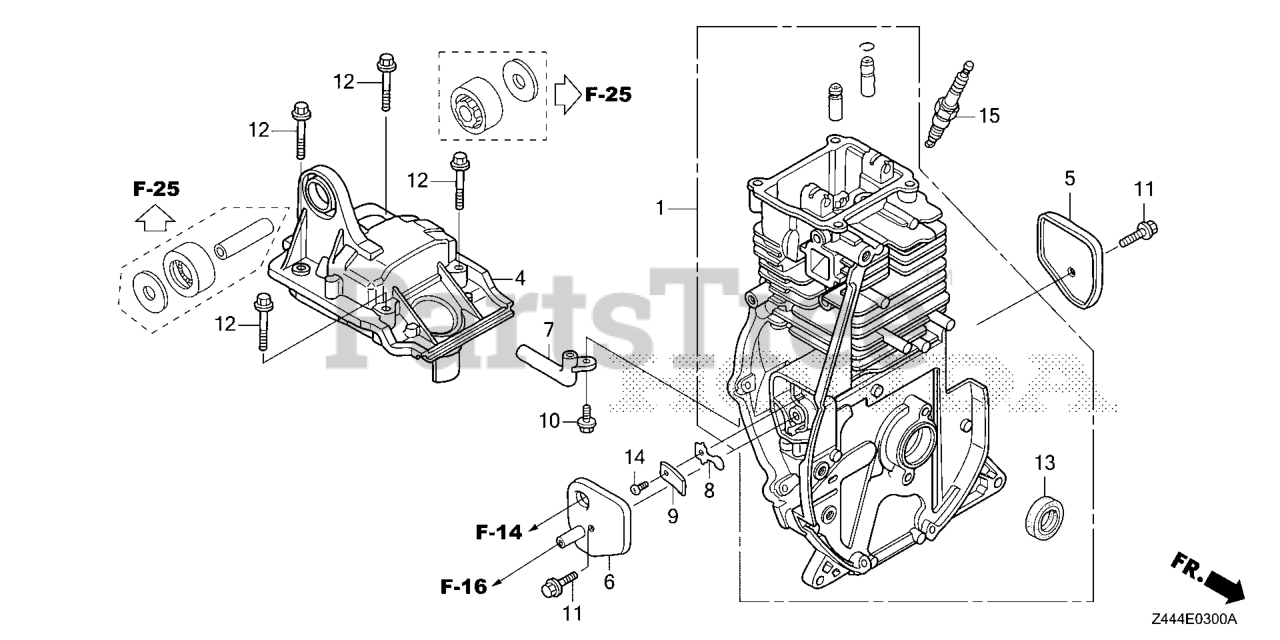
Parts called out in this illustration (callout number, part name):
1	CYLINDER ASSY.
4	COVER, HEAD
5	COVER A, BREATHER
6	COVER B, BREATHER
7	PIPE, BREATHER
8	VALVE, OIL OUTLET
9	PLATE, STOPPER
10	BOLT (4X10)
11	BOLT, FLANGE (6X14)
12	BOLT, FLANGE (6X28) (CT200) Use up to Engine SN 1530314.
13	OIL SEAL (22X35X6)
14	SCREW, PAN (3X5)
15	SPARK PLUG (CR4HSB) (NGK)
15	SPARK PLUG (CR5HSB)
